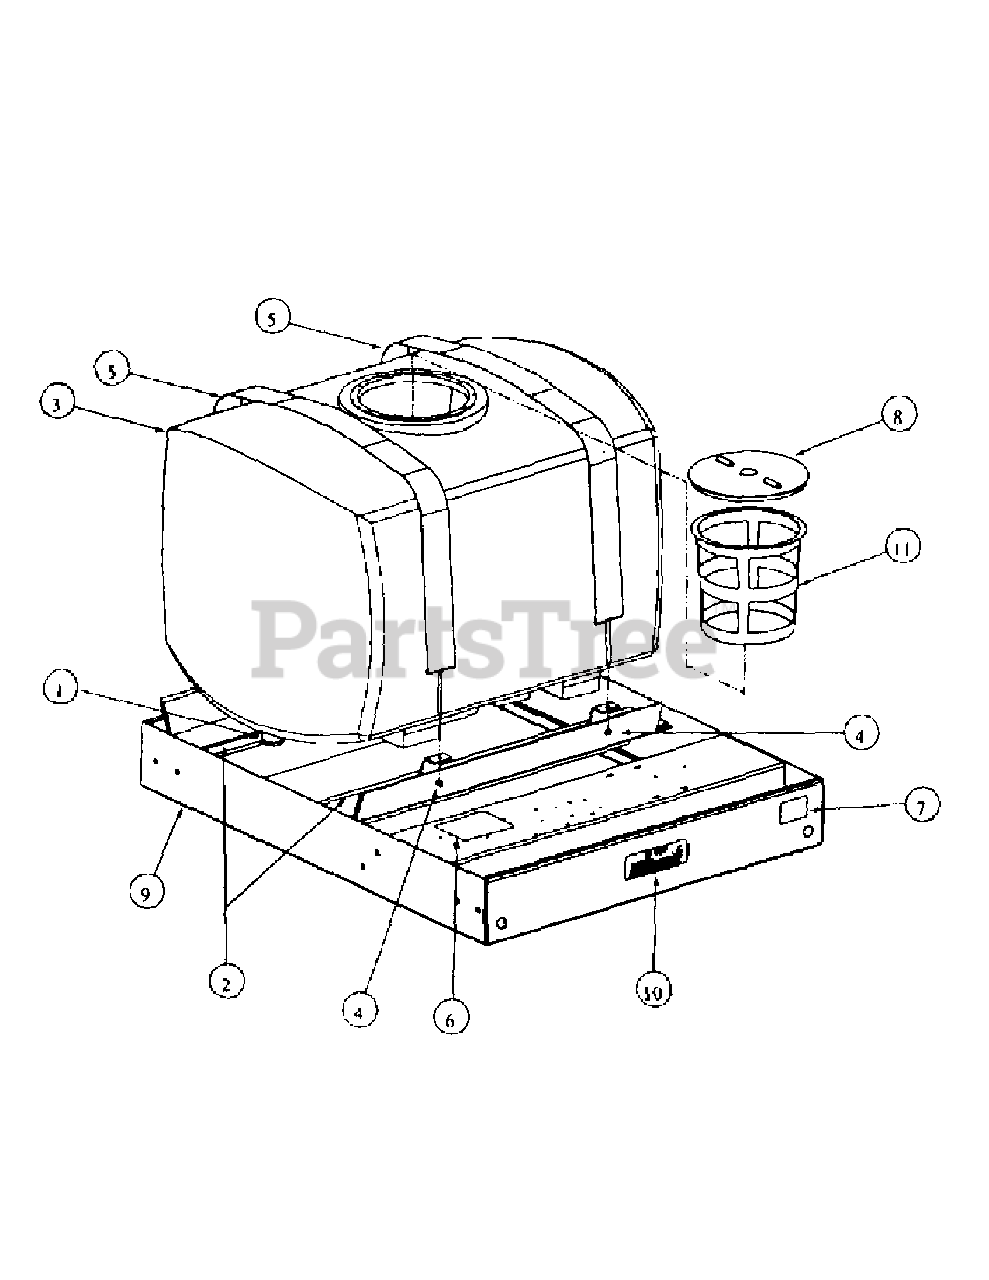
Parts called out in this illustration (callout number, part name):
1	Adapter, PVC, 1.25 NPT, 1 NPT
2	Foam, Adhesive Backed, 4" x 1/4" by ft
3	100 Gal. Poly Tank w/Lid
4	Nut, Nylock 5/16 - 18
5	Tank Strap Assembly
6	Decal Safety Procedures
7	Decal "Made in America"
8	Tank Lid
9	Main Frame Assembly
10	Decal, "SY 100, 2-1/4" x 7"
11	Strainer Basket, 10"
